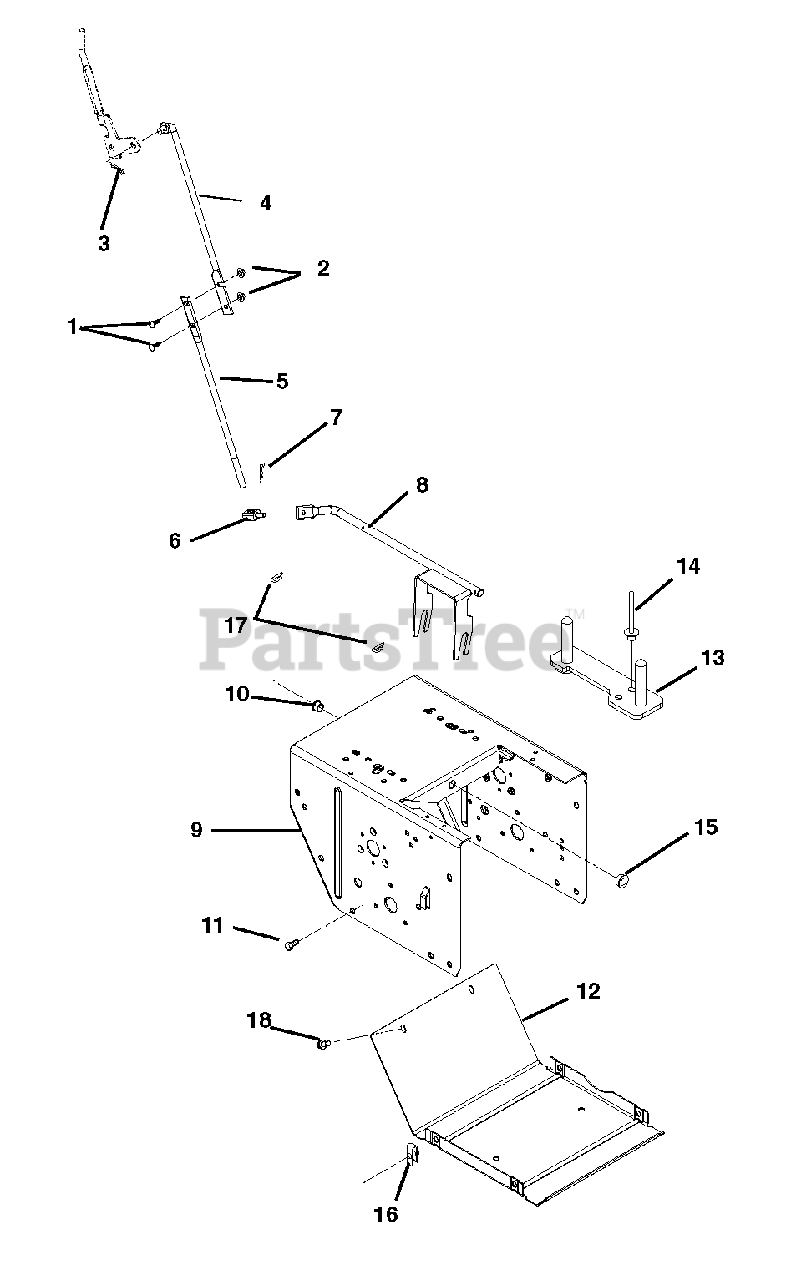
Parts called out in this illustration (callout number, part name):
1	Bolt, Round Head Square Neck .25-20 x .75 Grade 5
2	Nut, Locking Top Flange .25-20
3	Pin, Hair #25
4	Rod, Shift-Upper
5	Rod, Shift-Lower
6	Pivot, Shift Rod
7	Pin, Hair #25
8	Arm, Shift Weldment
9	Main Frame
10	Bushing, Polyliner .50 Split
11	Bolt, Hex Washer Head .25-20 x .75 Grade 5
12	Cover, Bottom
13	Bolt Strap
14	Rivet, Pop
15	Bushing, Polyliner .50 Snapin
16	Nut-Retainer .25-20 x .56
17	Clip, Spring
18	Screw, Tapping .25-20 x .50 Hex Washer Head
